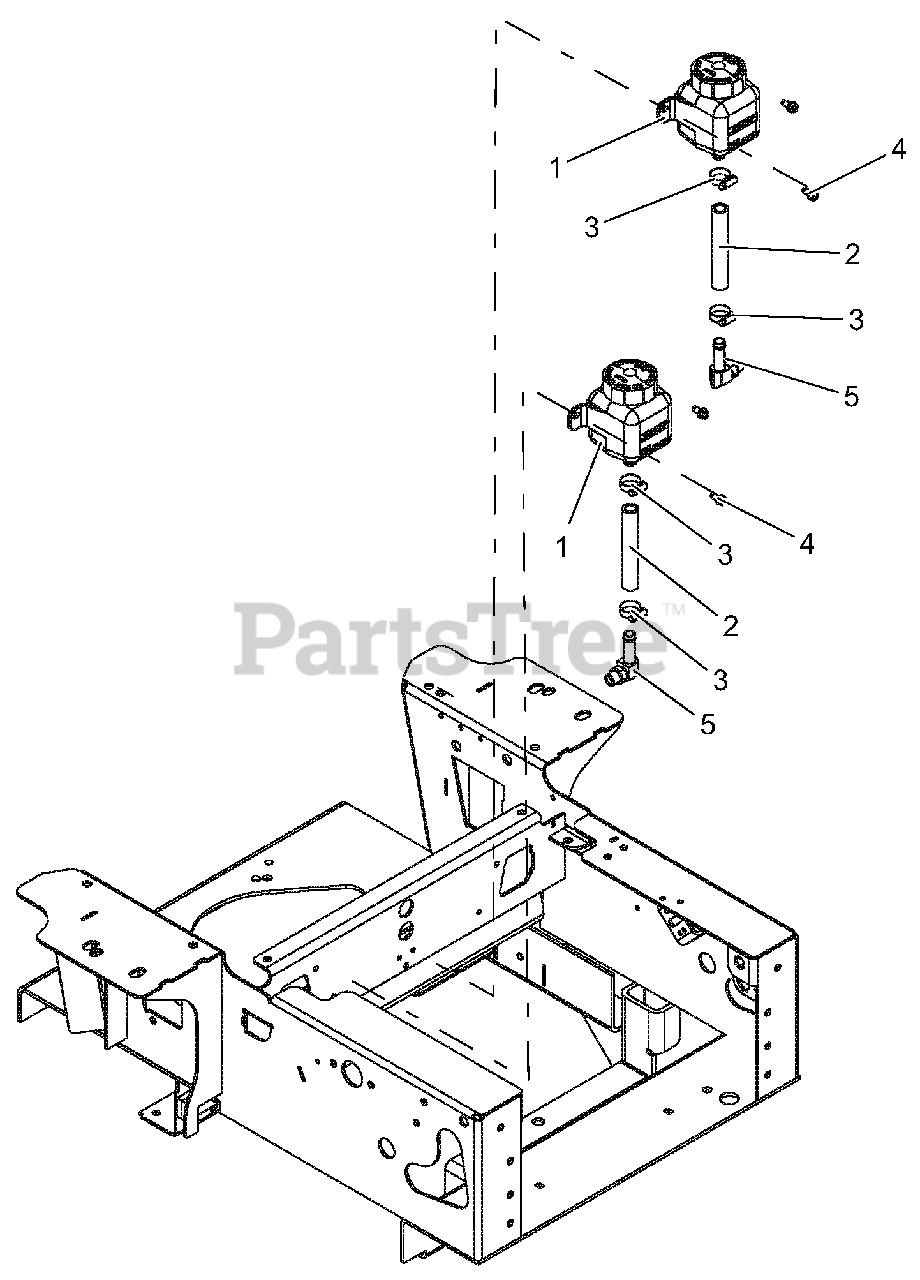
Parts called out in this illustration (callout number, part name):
1	TANK, EXPANSION ZT2800
2	HOSE, PT100 HYDRO OVERFLOW
3	CLAMP, .88 DIA HOSE
4	SCR-TAP .25-20X.50 HWH TR YWZ
5	FITTING, HYD (90 DEG)
